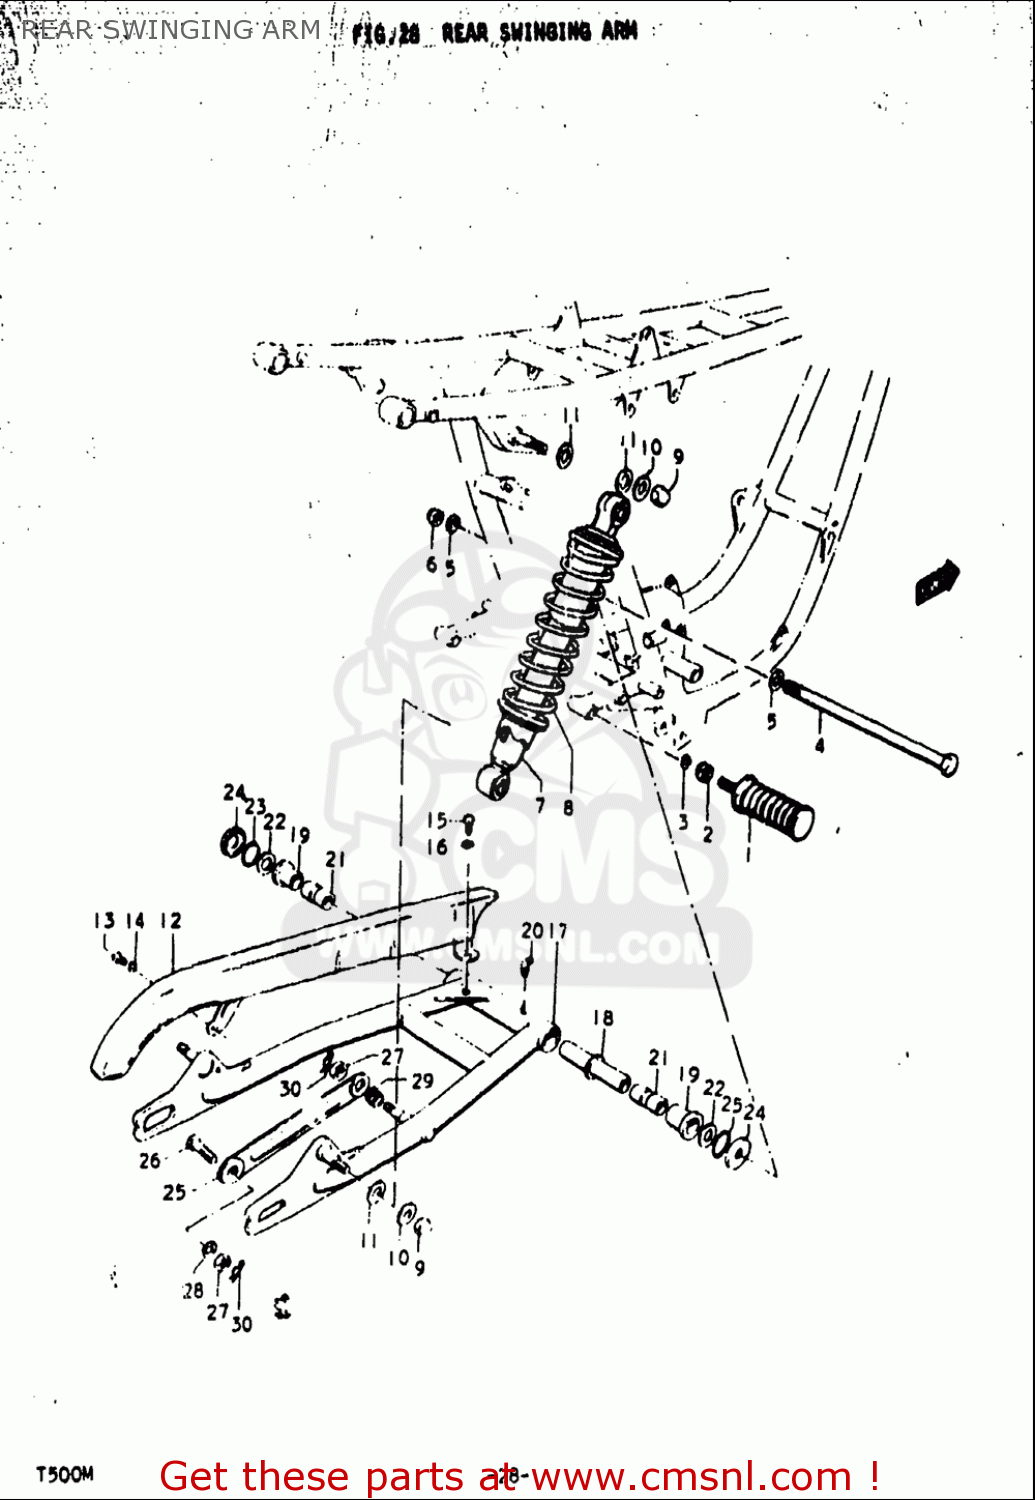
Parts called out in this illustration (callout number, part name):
1	BAR,FOOTREST RUBBER
2	NUT
3	WASHER,LOCK
4	SHAFT,REAR SWING ARM
5	WASHER
9	NUT
10	WASHER
11	WASHER (10.5X24X2.3)
13	SCREW(5X12)
14	TOOTHED WASHER
15	BOLT
16	WASHER,LOCK
19	BUSH
20	NIPPLE,GREASE
21	SPACER
22	WASHER(14.5X29X2.3)
23	O RING(D:3,ID:29.5)
24	COVER
26	BOLT(10X31)
27	NUT
28	WASHER,LOCK
29	SPRING
30	CLIP
